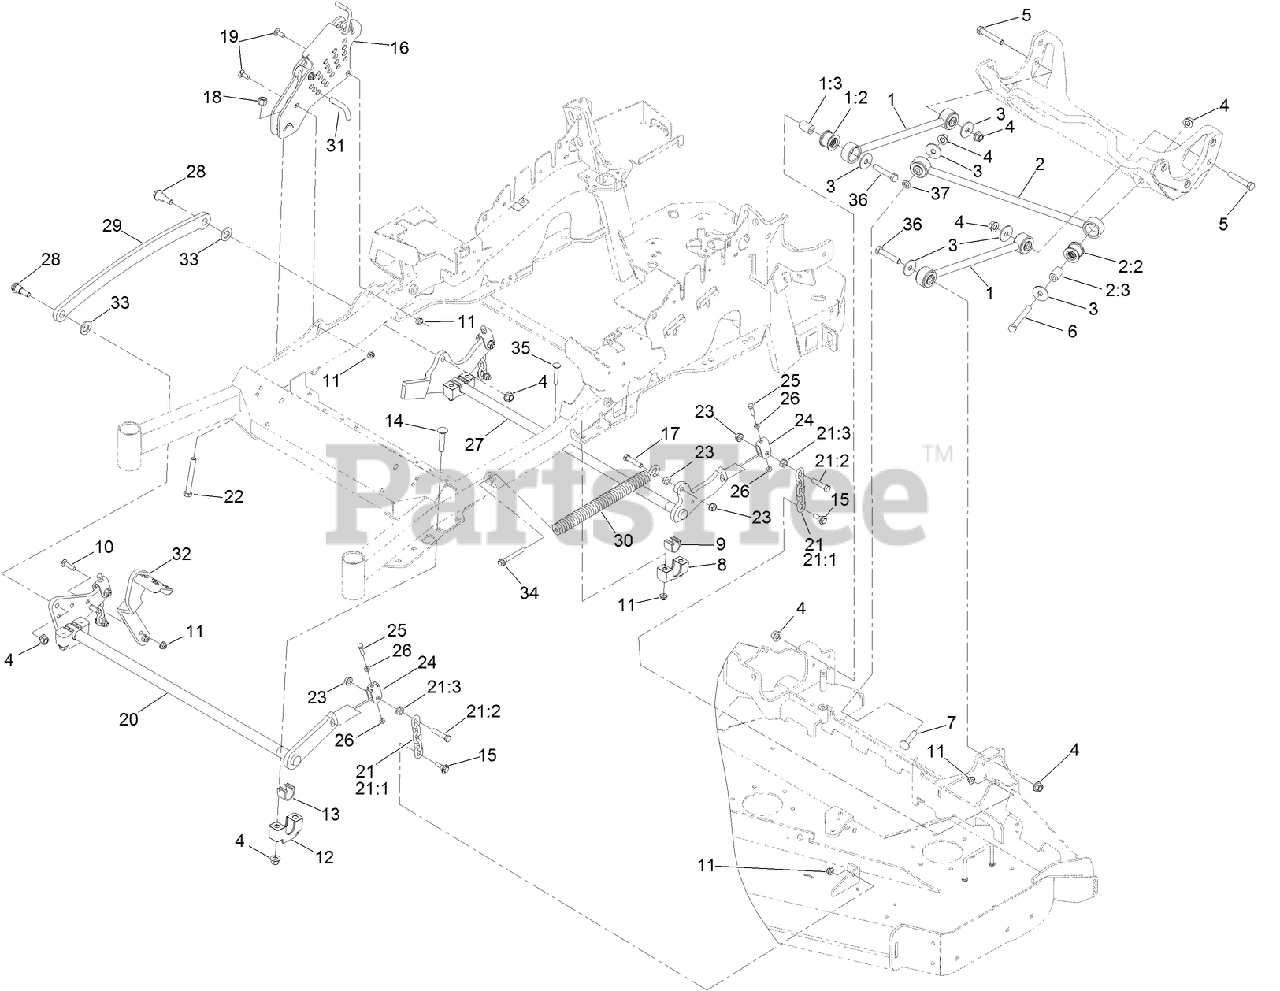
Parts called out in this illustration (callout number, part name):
1	DECK STRUT ASM
1:2	BUSHING-SUSPENSION, RUBBER
1:3	SPACER
2	PANHARD ROD ASM
2:2	BUSHING-SUSPENSION, RUBBER
2:3	SPACER
3	WASHER-THRUST
4	NUT-LOCK
5	SCREW-HH
6	SCREW-HH
7	SCREW-CARR
8	SUPPORT-CROSS SHAFT, BEARING REAR
9	BEARING-CROSS SHAFT, REAR
10	SCREW-HH
11	NUT-HF, NI
12	SUPPORT-CROSS SHAFT, BEARING
13	BEARING-CROSS SHAFT, FRONT
14	BOLT-CARR
15	SCREW-SHOULDER, HHF
16	HOC ASM
17	SCREW-HH
18	NUT-LOCK, NI
19	SCREW-HH
20	DECKLIFT-FRONT
21	DECK LIFT CHAIN ASM
21:1	CHAIN-LIFT, DECK
21:2	SCREW-HH
21:3	NUT-HF
22	BOLT-TAP
23	NUT-HF
24	YOKE-ADJUST, DECK
25	SCREW-HH
26	NUT-JAM
27	LIFT-DECK, REAR
28	SCREW-SHOULDER, HHF
29	LINK-LIFT, DECK
30	SPRING-EXTENSION
31	PIN-HOC
32	LEVER-FOOT
33	WASHER-FLAT
34	BOLT-SHOULDER
35	SCREW-HH
36	SCREW-HH
37	NUT-PUSH
